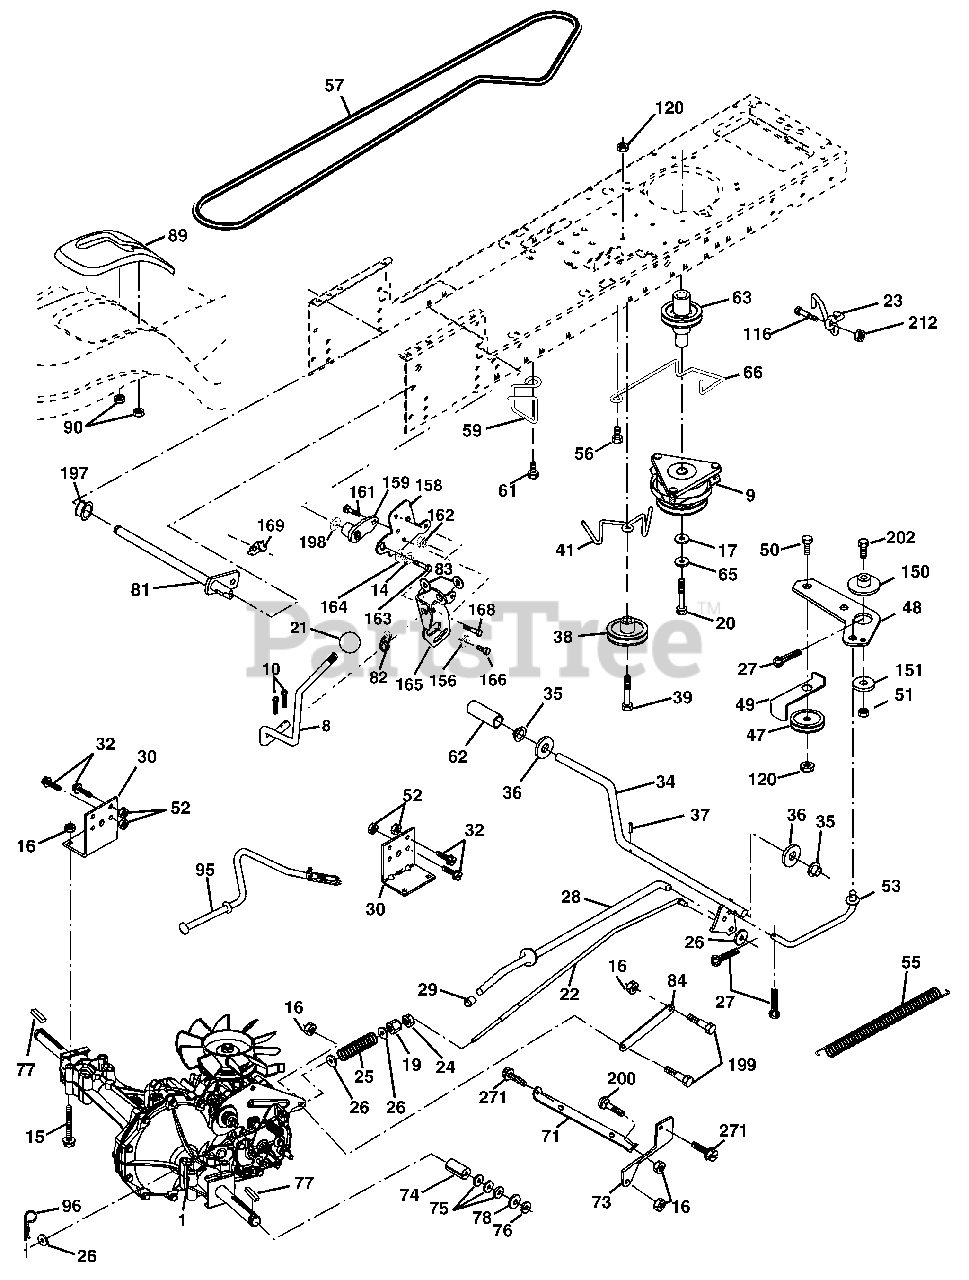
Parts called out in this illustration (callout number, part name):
8	Rod Shift Fender
9	Clutch Electric
10	Pin Cotter 1/8 x 1 CAD
14	Washer Lock Hvy Helical
15	Bolt Hex Flghd. 5/16-18 Gr.5
16	Nut Lock Hex W/Ins. 5/16-18 Unc P
17	Washer 1-1/2 OD x 15/32 ID x .250
19	Nut Lock Hex W/Wsh 3/8-16 Unc
20	Bolt, Hex 7/16-20 x 4 x Gr. 5-1.5
22	Rod, Brake Hydro
23	Bracket Asm Anti Rot
24	Locknut
25	Spring, Brake Rod
27	Pin Cotter 1/8 x 3/4 CAD.
28	Rod, Parking Brake
29	Cap,Parking Brake
30	Bracket, Transaxle
32	Bolt Hex Hd 5/16-18 Unc x 3/4
34	Shaft, Foot Pedal
35	Bearing, Nylon
37	Pin, Roll
38	Pulley, Composite, Flat
39	Bolt RDHD 3/8-16 UNC x 2-3/4 Gr. 5
41	Keeper, Belt Idler Flat
47	Pulley, Idler, V-Groove
48	Bellcrank Grnd Clutch
49	Retainer, Belt
50	Bolt Carr. Sh. 3/8-16 x 1-1/2 Gr. 5
51	Nut
52	Nut Crown Lock 5/16-18
53	Link, Clutch
55	Spring, Return, Clutch
56	Screw 3/8-16 x 1-1/4
57	V-Belt, Ground Drive
59	Keeper, Center Span
61	Screw 3/8-16 x .875 SMGML Tap/R.Z
62	Cover, Pedal
63	Pulley, Engine
65	Washer
66	Keeper Belt Engine Hydro
71	Strap Torque Lh Hydro
73	Strap Torque Rh Hydro
75	Washer 25/32 x 1-1/4 x 16 Ga.
78	Washer 25/32 x 1-5/8 x 16 Ga.
81	Shaft Asm Cross Tapered 510 20"
82	Spring Torsion T/A
83	Washer 17/32 x 3/4 x 16 Ga.
84	Link Transaxle HB-0510
89	Console, Shift
90	Nut, Self Thd Wsh Hd 1/4 Zinc
95	Control Asm. Bypass Hydro
96	Retainer Spring 1" Zinc/Cad
116	Bolt Rd Hd Sqnk 3/8-16 Unc x 1
120	Nut Lock Flg 3/8-16
150	Spacer Retainer
151	Washer 13/32 x 2 x 10 Ga.
156	Washer Srrted 5/16ID x 1.125
158	Bracket Shift Mount
159	Hub Shift
161	Bolt Rdhd Sqnk 1/4-20 x 3/4 Gr 5
162	Nut Crownlock 1/4-20 Unc
163	Bolt Hex Fin 1/4-20 Unc x 1 Gr 5
164	Washer 9/32 x 3/4 x 10 Ga.
165	Bracket Pivot Lever
166	Screw 5/16-18 x 5/8
168	Bolt Shoulxder 5/16-18 x .561
169	Plate Fasteneing Lt
197	Nylinder Snap-In
198	Washer Nyl. 7/8 ID x .105"
199	Bolt Shoulder 5/16-18
200	Bolt Rdhd Sqnk 5/16-18 x 1
202	Bolt Rdhd 3/8-16 x 1-3/4 Gr 5
212	Nut Hex Flange Lock
271	Screw Hex Wsh Thdr 3/8-16 x 3/4 BL
